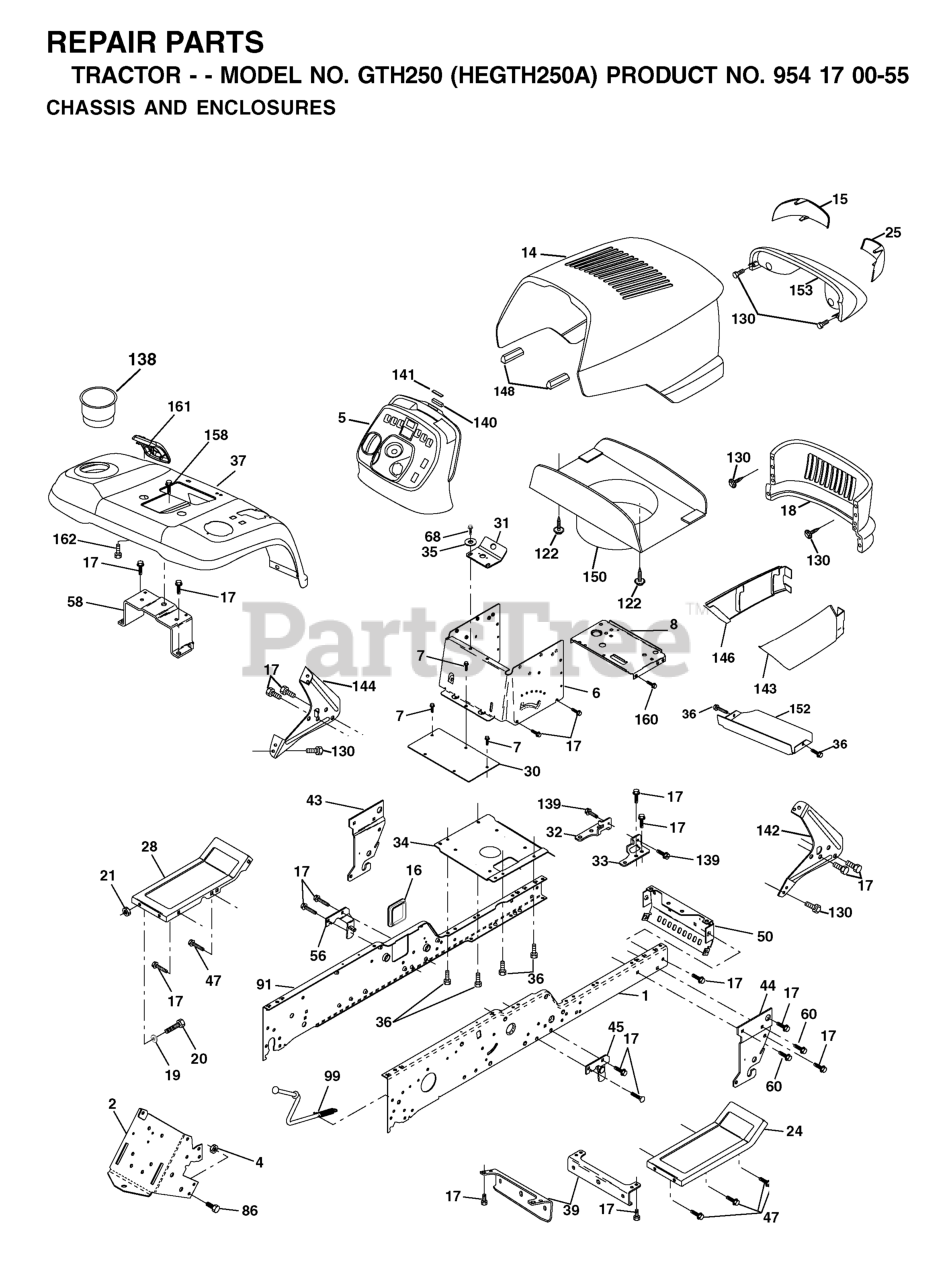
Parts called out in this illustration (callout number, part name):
1	FRAME RAIL RH
2	DRAWBAR, GT
4	Nut, Crownlock Hex 7/16-14 unc
5	DASH.STEALTH.YTGT.2CYL.BLK
6	DASH VGT, LOWER
7	SCREW
8	SUPPORT, BATTERY
14	HOOD ASM.
15	LENS RH
16	COVER ACCESS
17	SCREW 3/8-16X3/4
18	GRILLE
19	WASHER
20	BOLT
21	NUT
24	FOOTREST PNT RH
25	LENS LH
28	FOOTREST PNT LH
30	SADDLE.HYDRO.95
31	BRACKET SUPT 1-PC VGT STEERING
34	PLATE ASM ENG CHASSIS
35	WASHER
36	SCREW 5/16"
37	FENDER, PNT
39	BRACKET AXLE, FRONT
43	FRONT SUSPENSION BRKT LH
44	FRONT SUSPENSION BRKT RH
45	BRACKET, ASM., SUSP CHASSIS RH
50	BRACKET, CHASSIS FRONT
56	BRACKET ASM., SUSP CHASSIS LH
58	BRACKET ASM, FENDER
60	SCREW.3/8-16
68	Screw 5/16-18 x 1/2 Hex, Self Tapping 5/16-18 x 1/2
86	BOLT FIN HEX 7/16-14 X 1
91	FRAME RAIL LH
99	ROD ASM, BYPASS
122	SCREW.HEX.WS.HD.8-18 X 7/8
130	SCREW
138	CUPHOLDER
139	BOLT, SHOULDER 5/16-18
140	MAGNET STEALTH
141	STRIKER PLATE
142	BRACKET DASH STEALTH(R)
143	SKIRT GRILLE RH
144	BRACKET DASH STEALTH LH
146	SKIRT GRILLE LH
148	EXTRUSION BUMPER (3 2) (2 2)
150	DUCT HEAT HOOD
152	BROWNING SHIELD
153	Lens, Headlight Bar
158	SCREW 3/8-16X1/2
160	SCREW 5/16-18X1/2"
161	CONSOL.FUEL.WINDOW.BLACK
162	SCREW.HI-LO.CONSOLE
